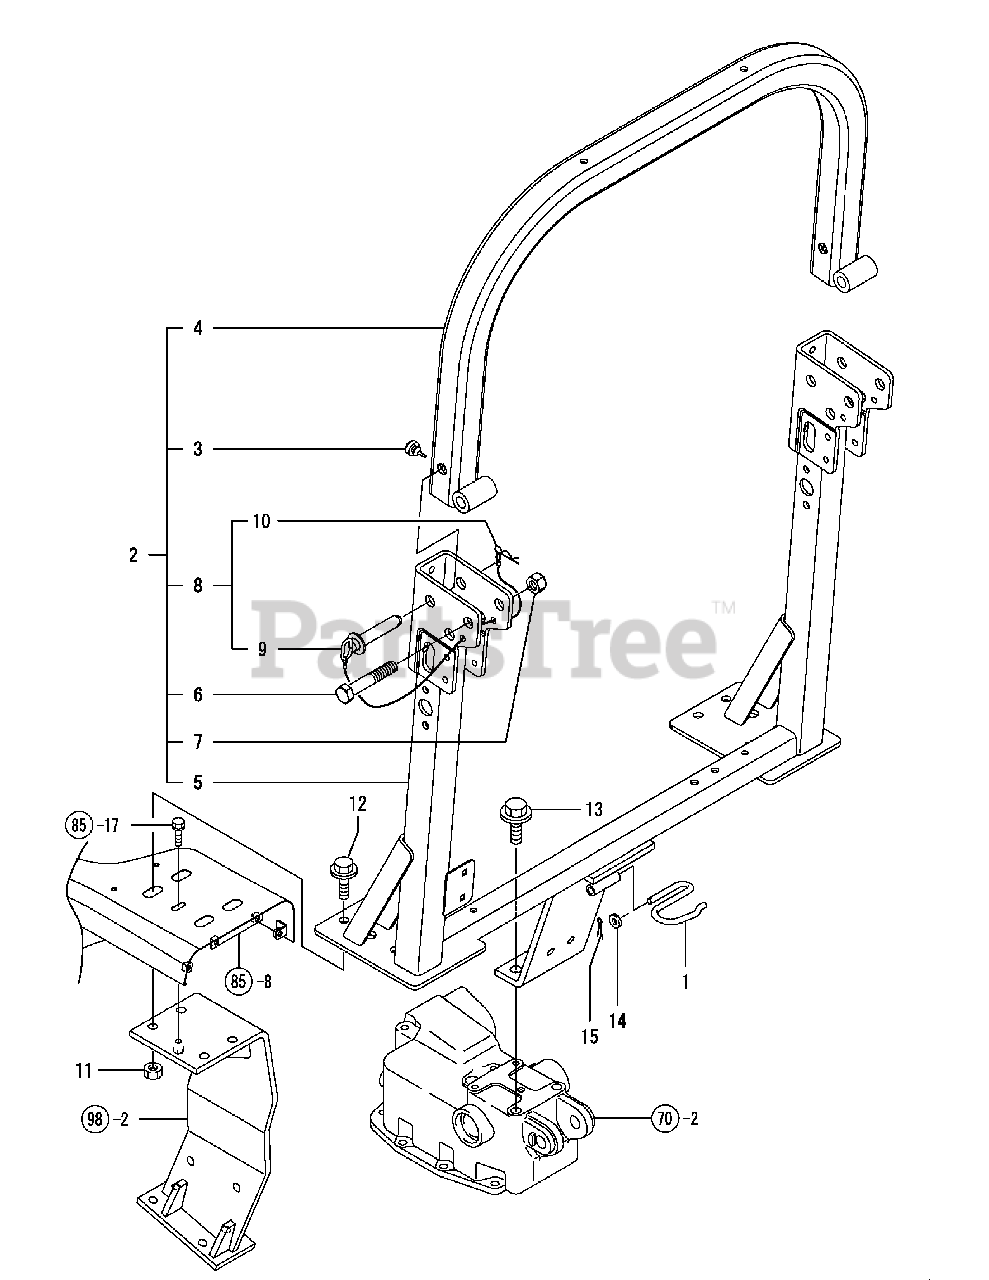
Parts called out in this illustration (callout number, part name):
2	Frame Assy, Upper
3	Stopper, Pedal
4	Frame Assy, Upper
5	Frame Assy, Upper
7	Nut, M16 (Nylock
8	Pin Assy, Stopper
9	Pin Stopper Cmp
10	Hitch Pin Clip
12	Bolt M12X 35 Plated
13	Bolt M14X 30 Plated
14	Washer 8, Polished
15	Cotter Pin 3.0X 25
16	Bolt M 8X 12 Plated
